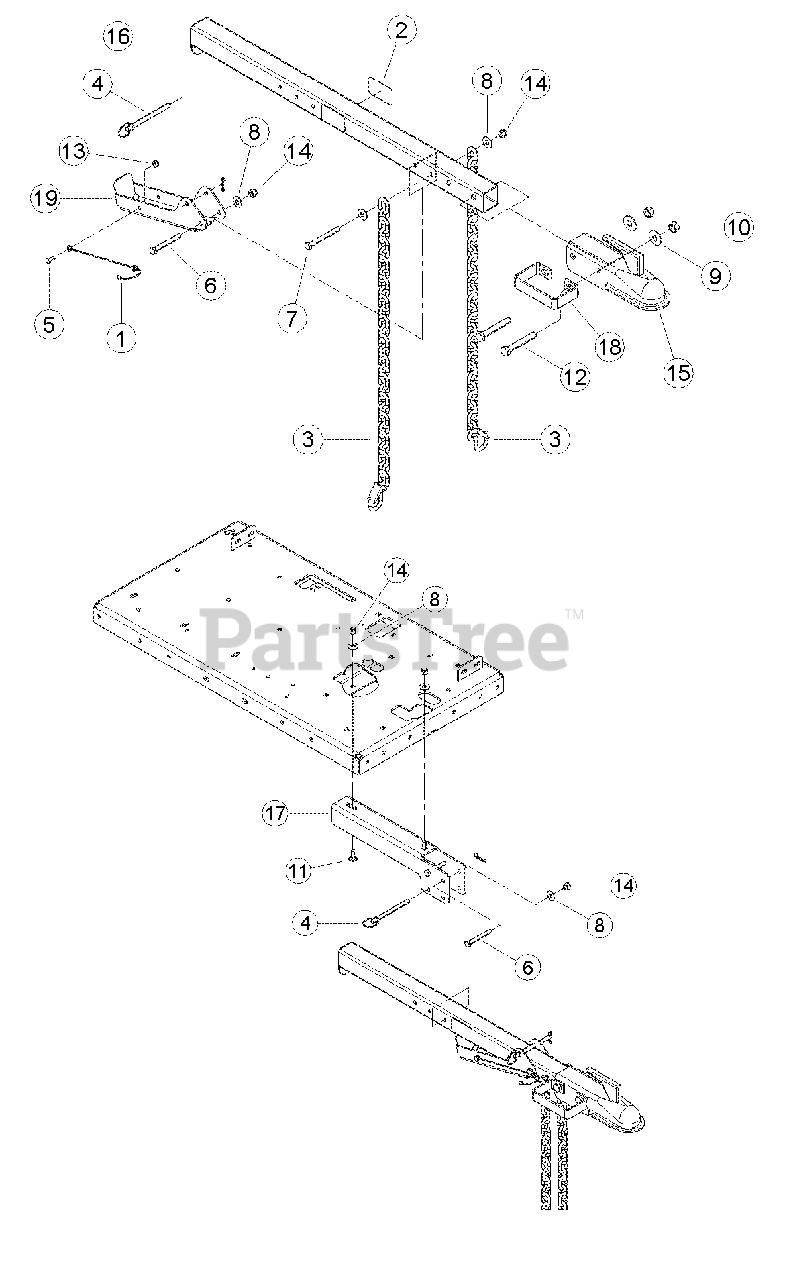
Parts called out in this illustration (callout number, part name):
1	LANYARD, NYLON
2	REFLECTOR, WIDE ANGLE AMBER
3	CHAIN, SAFETY 5000 LB W/LATCH
4	PIN, 3/8 HITCH
5	BOLT, 1/4 X 3/4 HEX HD GR5 ZP
6	BOLT, 3/8 X 3 HEX HD GR5 ZP
7	BOLT, 3/8 X 3-1/2 HEX HD GR5 ZP
8	WASHER, 3/8 FLAT ZP
9	WASHER, 1/2 FLAT ZP
10	NUT, 1/2 CENTERLOCK GRB ZP
11	BOLT, 3/8 X 1 CRG GR5 NC ZP
12	BOLT, 1/2 X 3-1/4 HEX HD GR5 ZP
13	NUT, 1/4 NE NYLOCK ZP
14	NUT, 3/8 NE NYLOCK ZP
15	TRAILER HITCH COUPLER
16	WELDMENT, HITCH POLE
17	CHANNEL, HITCH POLE
18	HANDLE, COUPLER
19	STAND, JACK
